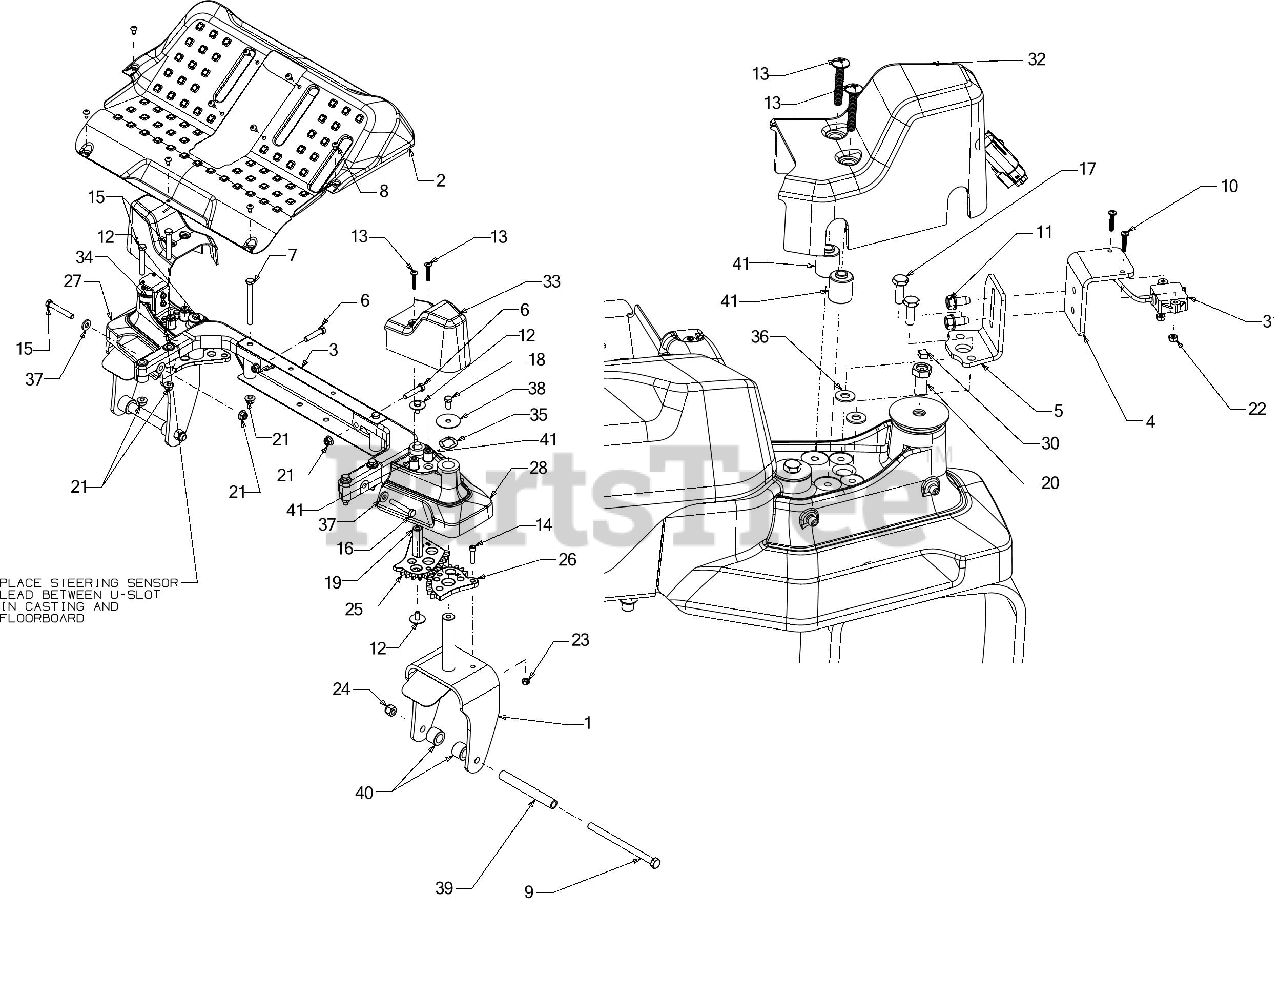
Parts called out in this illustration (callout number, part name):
1	CASTER WHEEL YOKE
2	FLOORBOARD
4	STEERING SENSOR BRACKET
5	SENSOR ADJUST BRACKET
6	HEX SCREW 3/8-16 x 1.75 GR5
7	HEX SCREW 3/8-16 x 4.00
8	SCREW 1/4-20 x .500
9	BOLT 1/2-20 x 7.25 GR5
10	SCREW #5-40 x .625
11	SCREW 1/4-20 X.500
12	SCREW 5/16-18 X.75 GR5
13	SCREW 1/4-20 x 1.50
14	SCREW 5/16-18X1.25
15	HEX SCREW-3/8-16X2.5 GR5
16	SCREW 3/8-16 x 2.25 GR5
17	SCREW 1/4-20X.75 GR5
18	SCREW 3/8-16 x .75 GR 5
19	STEERING GEAR PIVOT SHAFT
20	MAGNET MOUNTING BOLT
22	HEX LOCK NUT #5-4
23	HEX NUT
24	HEX NUT CENTER
25	STEERING GEAR
26	STEERING SPUR GEAR
27	AXLE PIVOT HOUSING (LH)
28	AXLE PIVOT HOUSING (RH)
30	ROTARY SENSOR MAGNET
31	ROTARY SENSOR
32	AXLE COVER (LH)
33	AXLE COVER (RH)
34	FLAT WASHER
35	WAVE WASHER
36	FLAT WASHER
37	FLAT WASHER
38	HUB CAP WASHER .406 x 1.92 x .060
39	CASTER SPACER
40	HUB:76 x 1.23X.92 LG
41	SHOULDER SPACER
